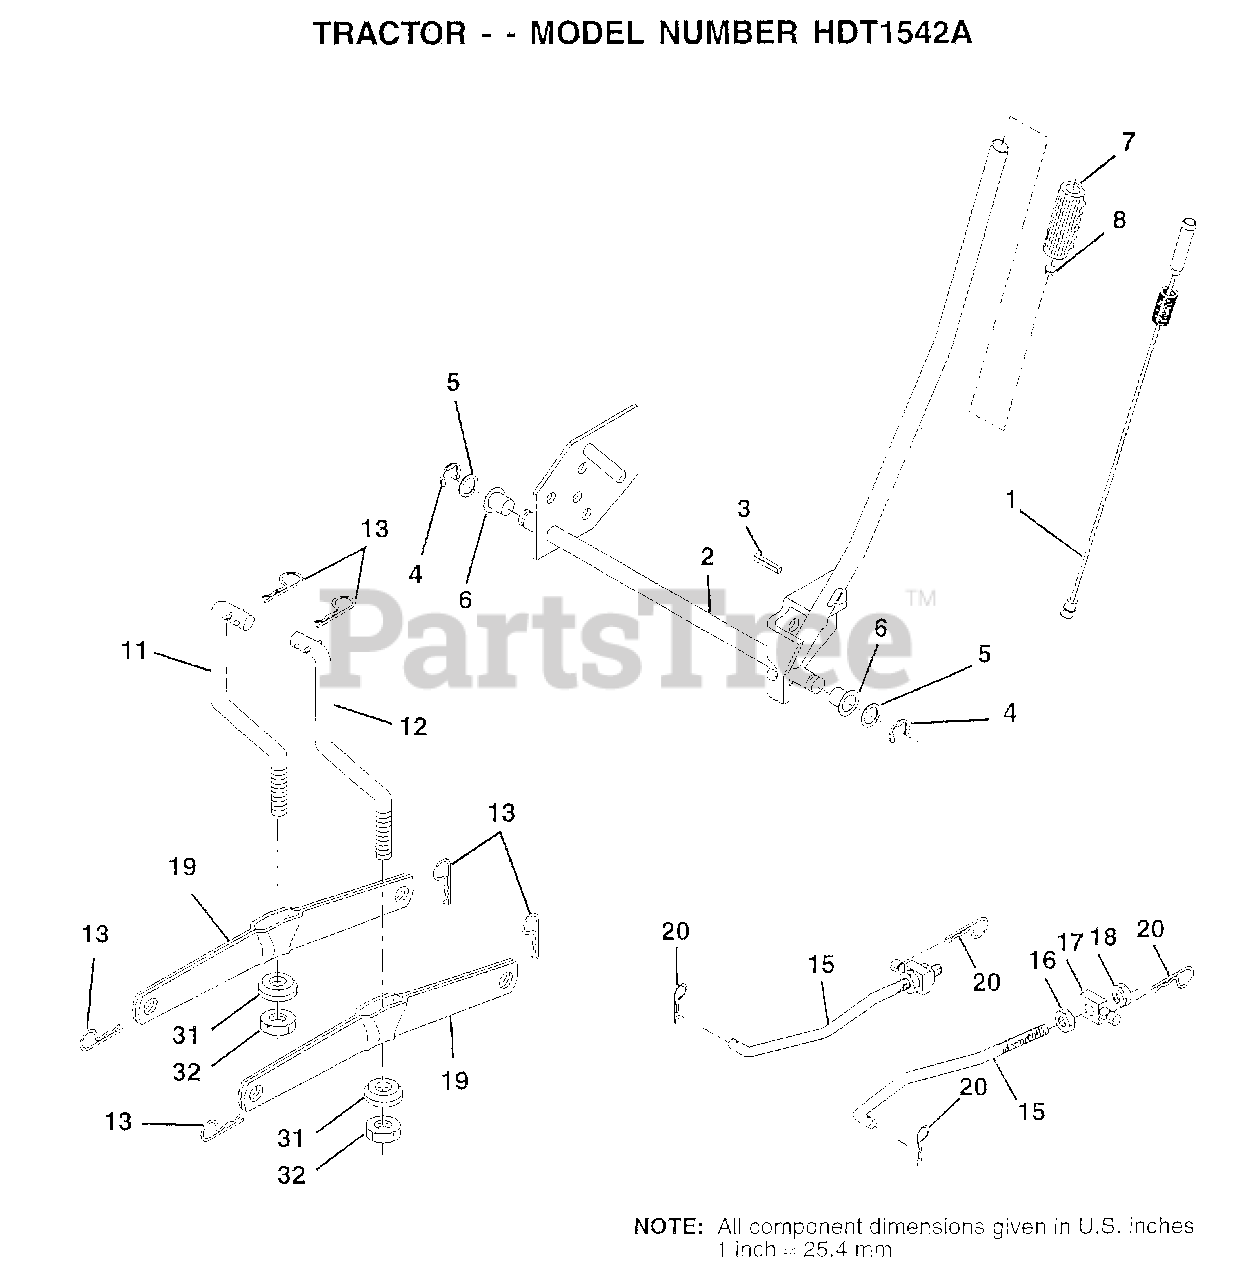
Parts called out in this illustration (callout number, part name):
1	WIRE ASM W.SPRING
2	"SHAFT ASM LIFT,RH"
3	PIN-GROOVE LT
5	WASHER
6	NYLON BEARING
7	GRIP
15	LINK.FRONT
16	NUT
17	TRUNION
18	NUT LTV
19	ARM SUSP REAR
20	RETAINER SPRING
31	BEARING PVT LH
32	NUT.CROWNLOCK.3/8
